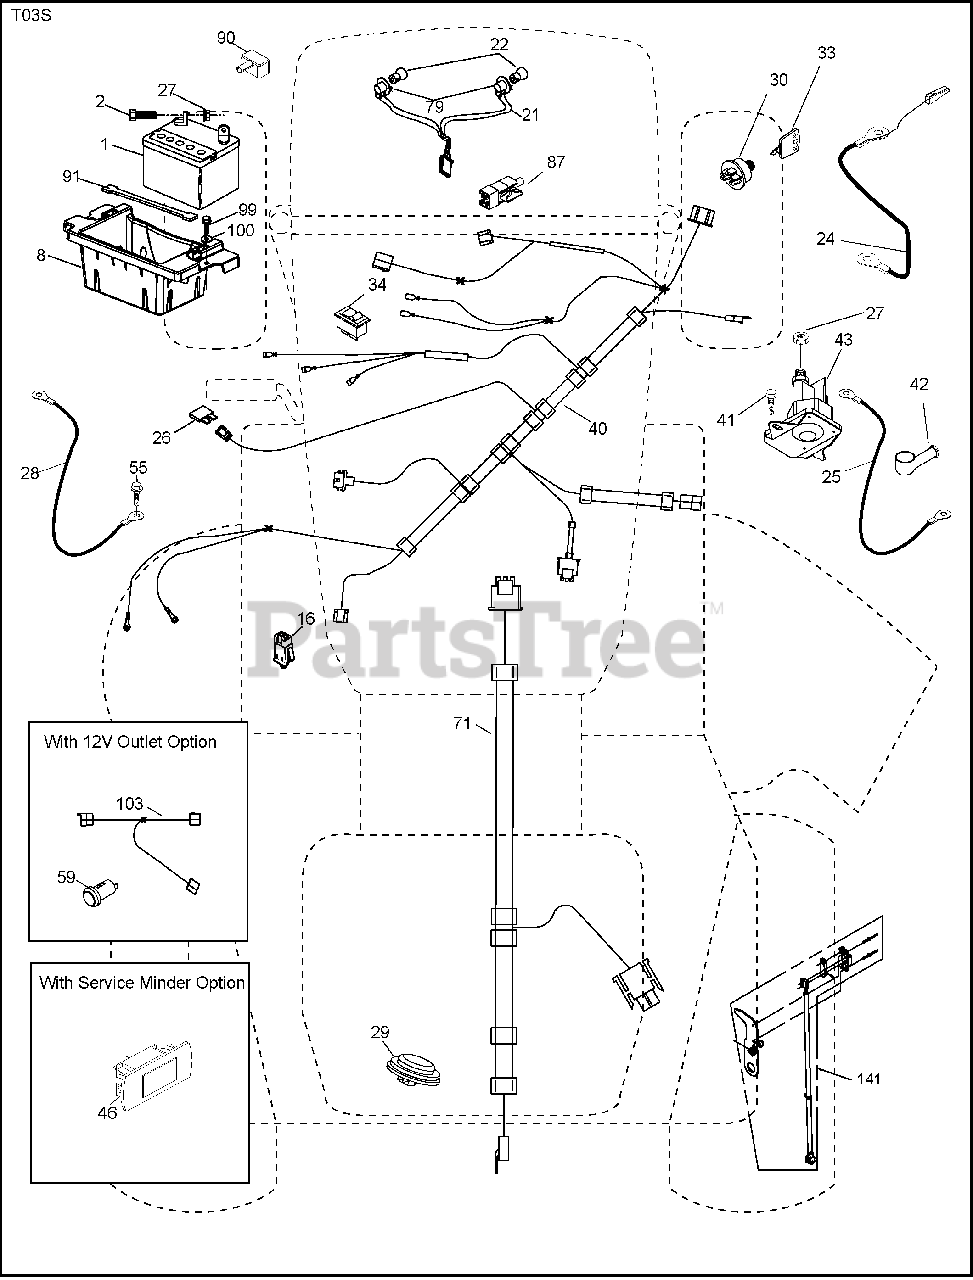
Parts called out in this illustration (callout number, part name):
1	Battery
2	Bolt Hex Head 1/4-20 x 3/4
8	Box Battery
16	Switch Interlock Push-In
21	Harness Socket Light w/4152J
22	Bulb Light
24	Cable Battery
25	Cable Starter
26	Fuse
27	Nut Keps Hex 1/4-20 unc
28	Cable, Ground
29	Switch, Seat
30	Switch, Ign.
33	Key/Chain
34	Switch Light/Reset
40	Harness Ign.
41	Screw Thd. Cut 1/4-20 x 1/2
42	Cover, Terminal
43	Solenoid
46	Gauge Hourmeter
55	Screw Thdrol. 5/16-18 x 3/4 TYTT
71	Harness Ign. Dash
79	Socket Asm. Twistlock
87	Switch Interlock
90	Cover Terminal Battery
91	Strap Battery Mount Front
99	Screw Hexwsh Thdrol. 1/4-20 x 3/4
100	Washer 9/32 x 7/8 x 16 Ga.
141	Kit Lt. ROS
